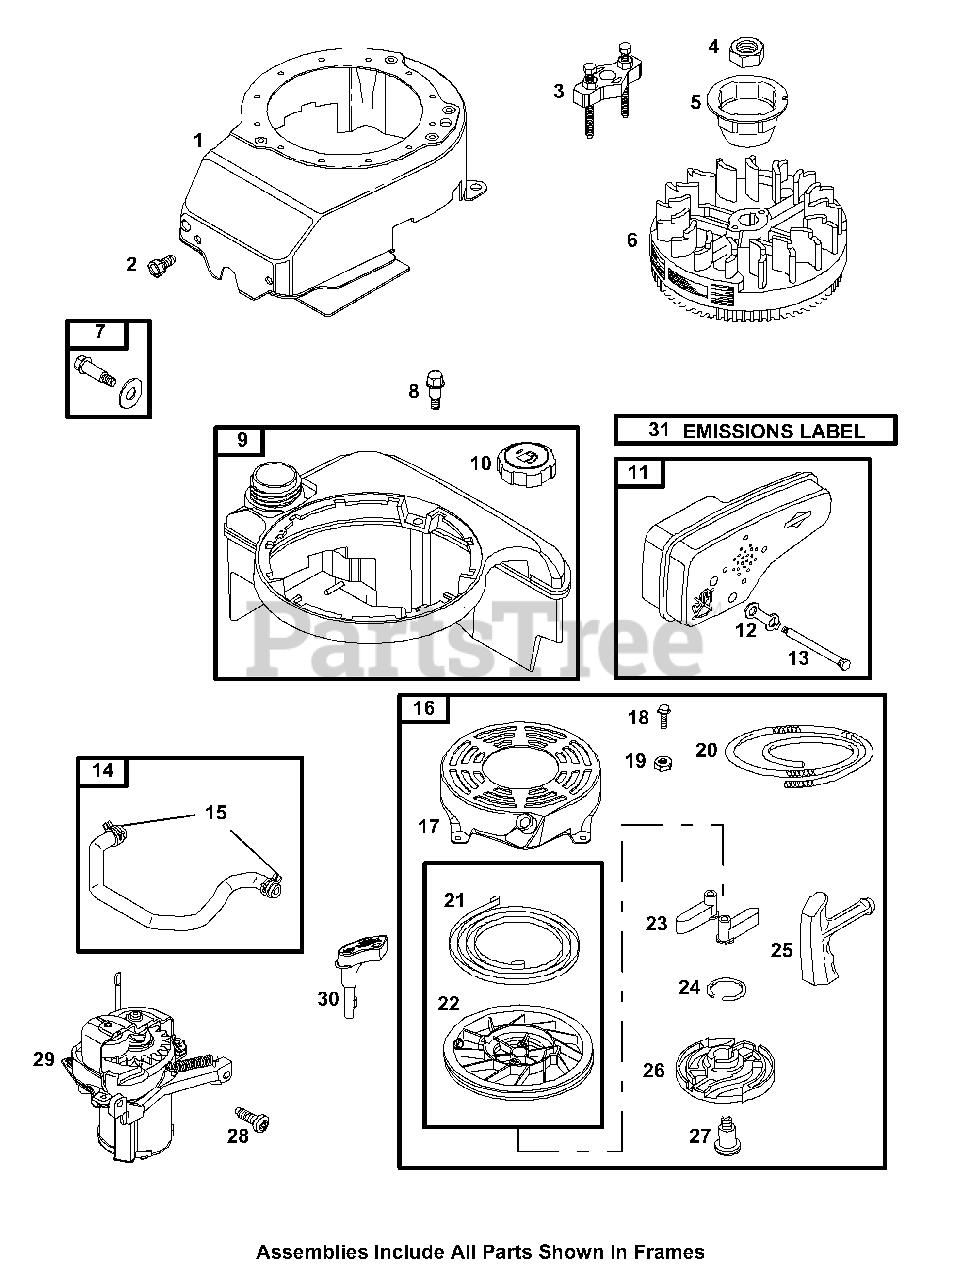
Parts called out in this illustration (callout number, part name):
1	Blower Housing
2	Screw (Blower Housing)
3	Flywheel Puller
4	Nut (Flywheel)
5	Flywheel Cup
7	Screw/Washer Kit
8	Screw (Fuel Tank)
9	Fuel Tank
10	Fuel Tank Cap
11	Exhaust Muffler
12	Muffler Screw Lock
13	Screw (Exhaust Muffler)
15	Hose Clamp
16	Rewind Starter
17	Rewind Starter Housing
18	Screw (Rewind Starter)
19	Nut (Rewind Starter Housing)
20	Starter Rope (Cut to Reqd. length)
21	Pulley/Spring Assembly (Spring)
22	Pulley/Spring Assembly (Pulley)
23	Ratchet Pawl
24	Friction Spring
25	Starter Rope Grip
26	Pawl Friction Plate
27	Screw (Pawl Friction Plate)
28	Screw (Starter Motor)
29	Starter Motor
31	Emissions Label
